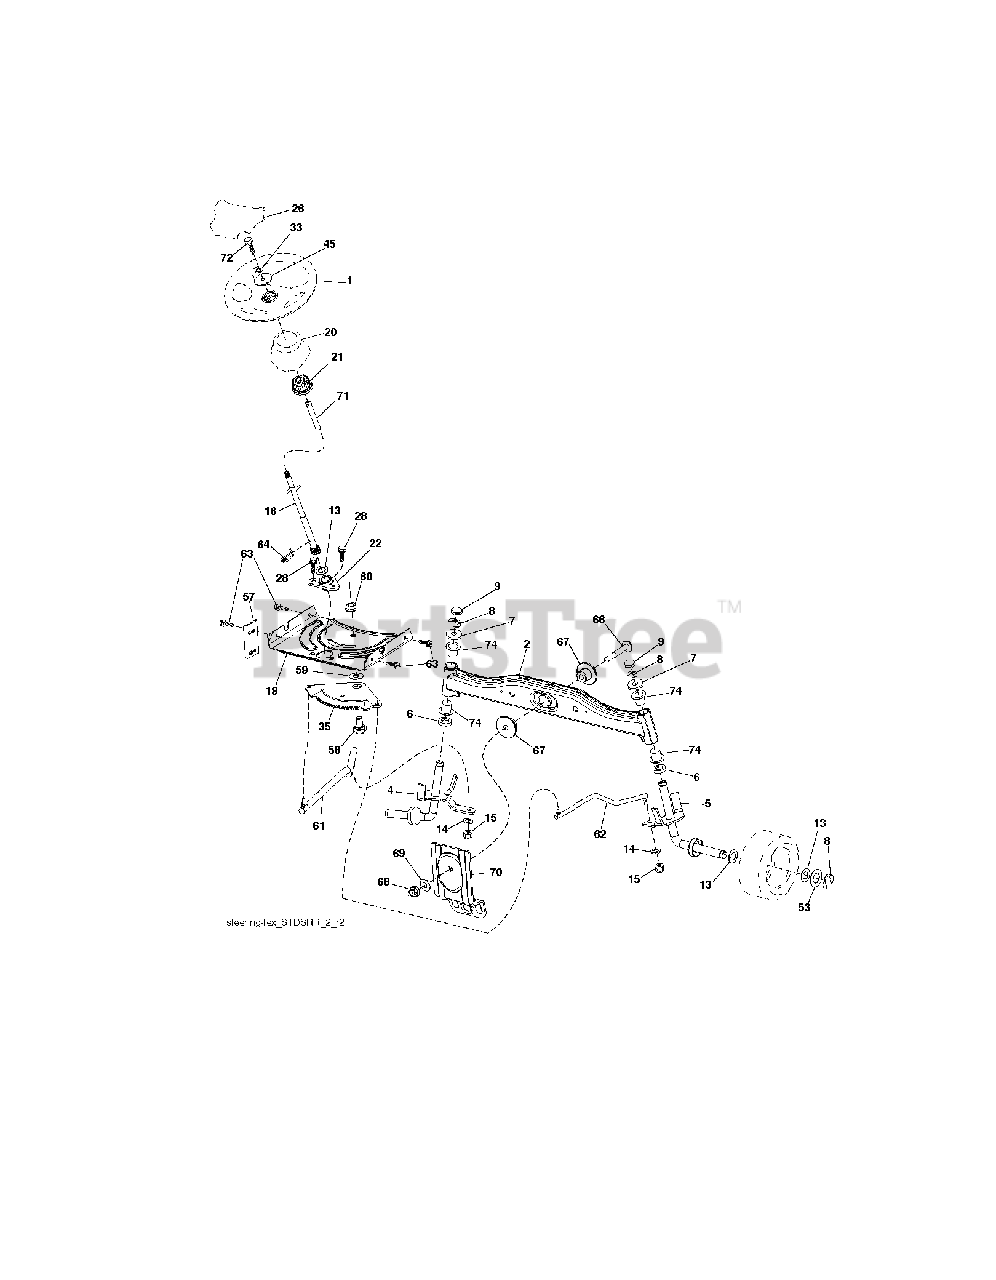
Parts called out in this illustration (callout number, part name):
1	WHEEL.STEERING.PREM.2.BLK
2	AXLE HALF ASM-WELDED
8	RING CLIP
9	CAP.SPINDLE
14	WASHER, LOCK 3/8
15	NUT CROWNLOCK 3/8-24
16	SHAFT.STEER.3/4.PLATED.TEX
19	PLATE.STEER.DDL.NLT/NG
20	BOOT.STEERING.PREDATOR.LT.BLAC
21	ADAPTER, WHEEL STNG..
22	STEERING.SUPT.LOWER.
26	INSERT.CAP.STRG.WH.BLACK
28	SCREW, 3/8-16X3/4
33	LOCKWASHER
35	GEAR.SECTOR.PLATE.DDL.
45	WASHER.11/32
53	WASHER.HARDENED
57	BRACKET.UPSTOP.TEX
58	BOLT.SHOULDER.SECTOR.P
59	WASHER.THURST.SECTOR.S
60	NUT FLANGE LOCK 5/8-11
61	DRAGLINK.LH.BALLSTUD.D
62	DRAGLINK.RH.BALLSTUD.D
63	SCREW
64	RETAINER.CLIP.SPRING.S
66	BOLT HEX FGHD 7/16-14 X 3 SERR
67	BUSHING.PM.FRONT AXLE
68	NUT.LOCK.FLANGE.7/16
69	WASHER.1.5X.505X.118
71	SHAFT.EXTEN.STRG.SPLINE
72	BOLT 5/16-18 X 4 W/PATCH
74	BRNG T
